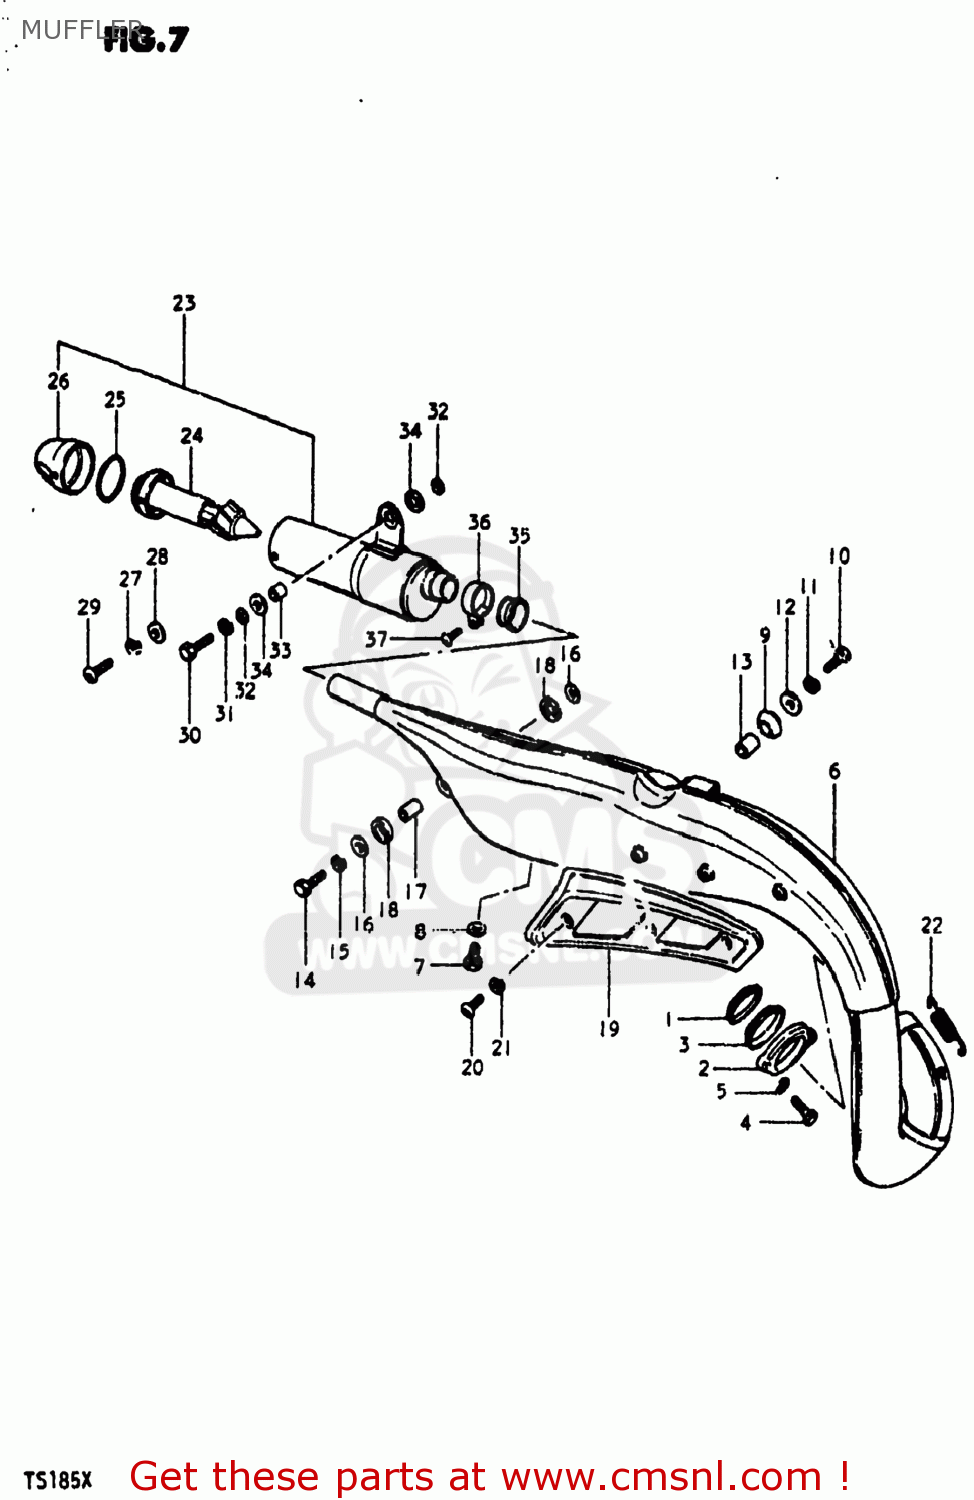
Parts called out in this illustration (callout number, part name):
1	GASKET,EXHAUST PIPE (NAS)
2	CLAMP,EXHAUST PIPE
3	CUSHION,EXHAUST PIPE
4	BOLT
5	LOCK WASHER
6	BODY,MUFFLER
7	BOLT 10X9
8	GASKET(10X14X3.6) (NAS)
9	DAMPER,MUFFLER,FR
10	BOLT
11	LOCK WASHER
12	WASHER
13	SPACER (8X12X15)
14	BOLT
15	LOCK WASHER
16	WASHER (8.2X20X1.6)
17	SPACER (8.6X13.8X9.8)
18	CUSHION
19	COVER,MUFFLER
20	SCREW
21	LOCK WASHER
22	SPRING
23	MUFFLER ASSEMBLY
24	TUBE,MUFFLER CLEAN OUT
25	O-RING (D:3.5 ID:54.4)
26	COVER,SECOND MUFFLER TAIL
27	SCREW(6X8)
28	LOCK WASHER
29	WASHER
30	BOLT
31	LOCK WASHER
32	WASHER
33	SPACER
34	CUSHION
35	CONNECTOR,MUFFLER
36	CLAMP
37	SCREW
